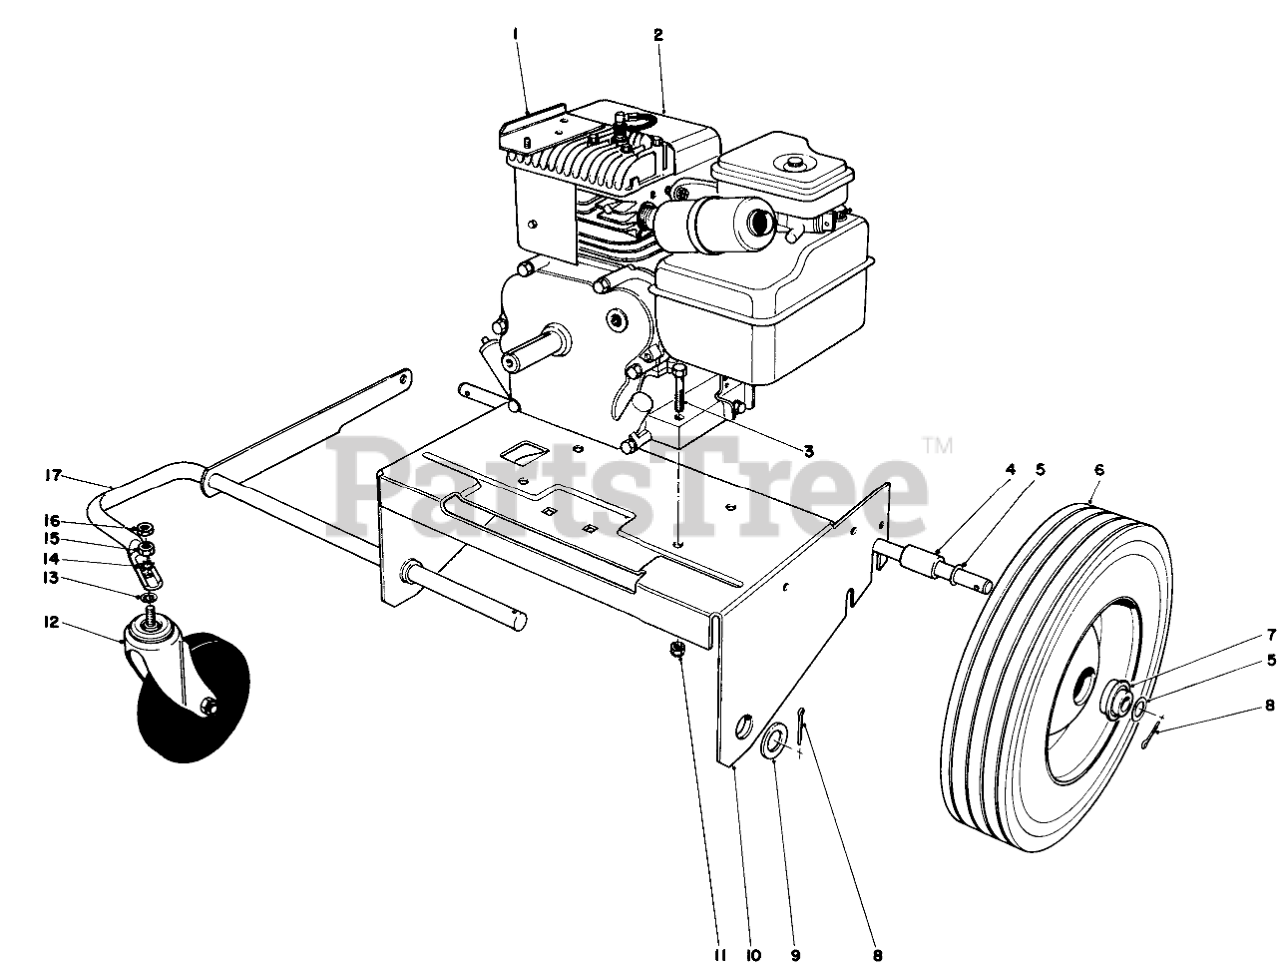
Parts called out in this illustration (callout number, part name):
1	MOUNTING BRKT WA
2	Engine
3	SCREW-HH
4	SPACER-AXLE
5	WASHER
6	WHEEL
7	BEARING
8	PIN-COTTER
9	WASHER-FLAT
10	Engine Plate
11	NUT-LOCK, CONE
12	CASTER
13	WASHER-LOCK/INT
14	WASHER-LOCK, EXT
15	NUT-HH
16	1/2-13 CONELOCK NUT
17	Front Wheel Support
